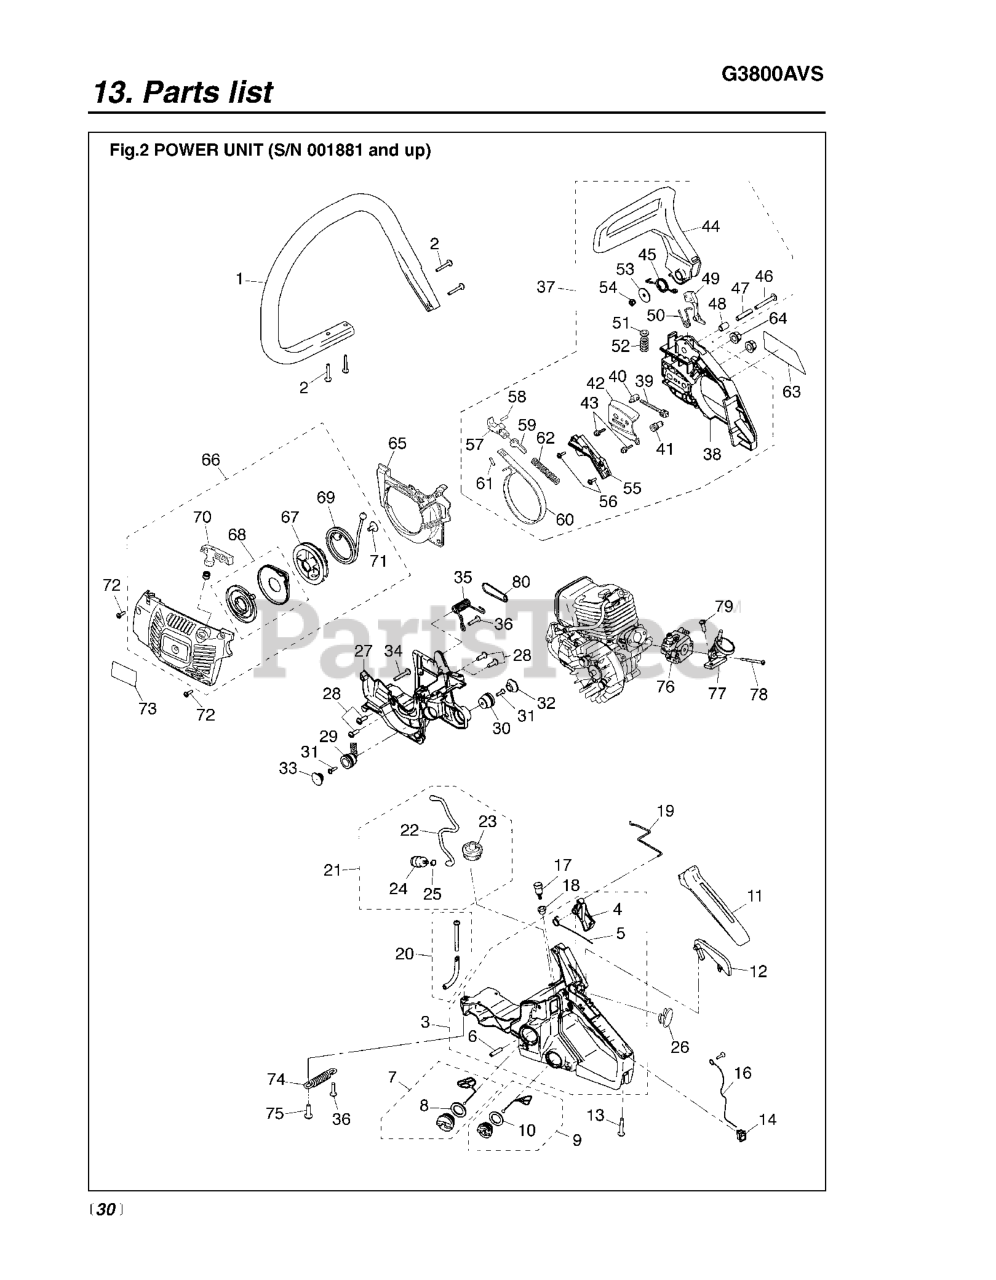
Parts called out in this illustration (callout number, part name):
2	SCREW
3	HANDLE, RIGHT ASSY
6	SPRING PIN
7	CAP
8	GASKET
10	GASKET
12	ARM (RPLS 335633350-335633352)
14	SWITCH
17	BREATHER
18	GROMMET
19	ROD.THROTTLE
20	PIPE COMP***
21	PIPE ASSY
22	PIPE
25	CLIP
27	CASE, ENGINE
28	RP_SCREW
36	SCREW (RPLS 267132210)
42	PLATE(B)
43	SCREW
45	RETURN SPRING
46	SCREW
47	SPACER, INNER
48	SPACER
50	SPRING
52	SPRING (RPLS 285154270)
53	WASHER
56	SCREW
57	BRAKE LEVER
58	ROLLER
59	ARM
60	BAND
61	ROLLER
62	SPRING
64	NUT FLANGE
66	STARTER-A
71	SCREW
74	SPRING(F)
75	RP_SCREW
76	CARBURETOR ASSY(RPL-T210881000
77	MANIFOLD
